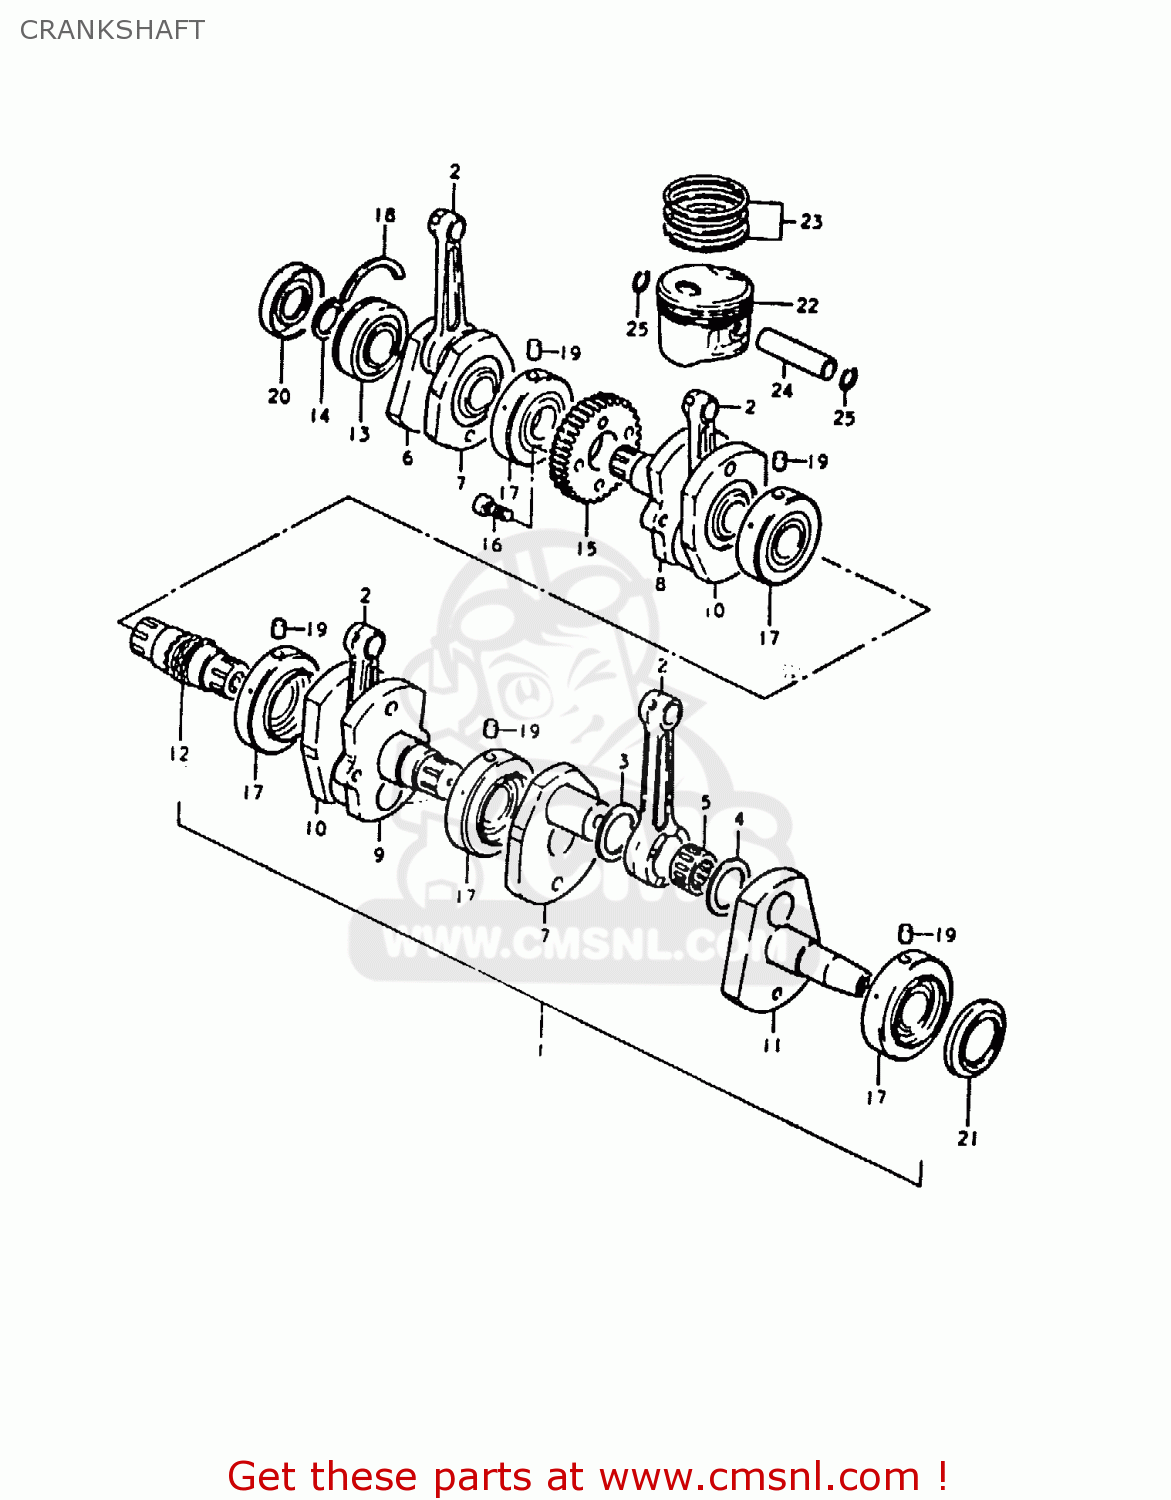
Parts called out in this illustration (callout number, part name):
1	CRANKSHAFT ASSEMBLY
2	ROD,CONNECTING
3	WASHER (29X48X2)
4	WASHER (29X48X1)
5	BEARING(29X39X20)
6	CRANKSHAFT
7	WEB,CRANK
8	CRANKSHAFT
9	CRANKSHAFT
10	WEB,CRANK,MIDDLE
11	CRANKSHAFT,LEFT
12	SHAFT,TIMING CHAIN DRIVE
13	BEARING(30X72X19)
14	CIRCLIP,30MM
15	GEAR,PRIMARY DRIVE
16	BOLT
17	BEARING
18	C RING
19	PIN
20	SEAL,OIL(30X72X11)
21	SEAL,OIL(47.3X60X6.5)
22	PISTON
23	RING SET,PISTON
24	PIN,PISTON (18MM)
25	CIRCLIP,PISTON PIN
